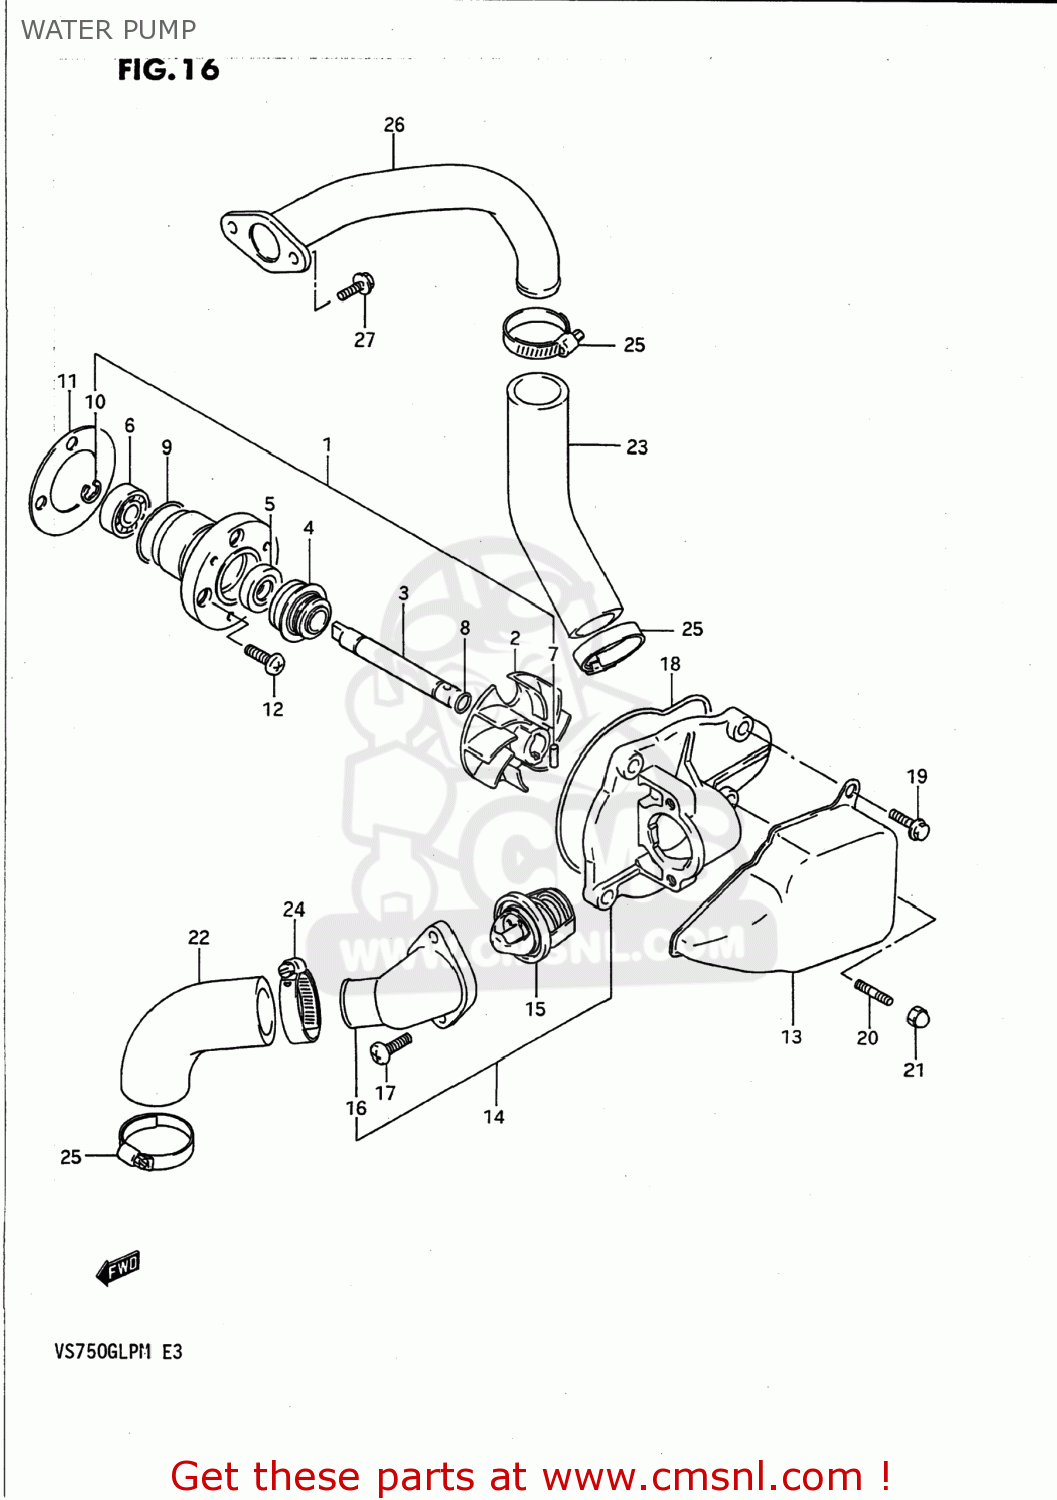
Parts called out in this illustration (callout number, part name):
1	PUMP ASSEMBLY,WATER
2	IMPELLER
3	SHAFT
4	SEAL,MECHANICAL
5	OILSEAL
6	BEARING,10X26X8
7	PIN
8	O RING
9	O RING
10	E RING
11	GASKET,WATER PUMP (NAS)
12	SCREW
13	COVER,WATER PUMP
14	CASE ASSY,WATER PUMP
15	THERMOSTAT,WATER
16	CONNECTOR
17	SCREW
18	O RING,WATER PUMP CAP
19	BOLT
20	STUD
21	NUT
22	HOSE,WATER PUMP IN
23	HOSE,WATER
24	CLAMP
25	CLAMP
26	PIPE,CYLINDER INLET
27	BOLT
